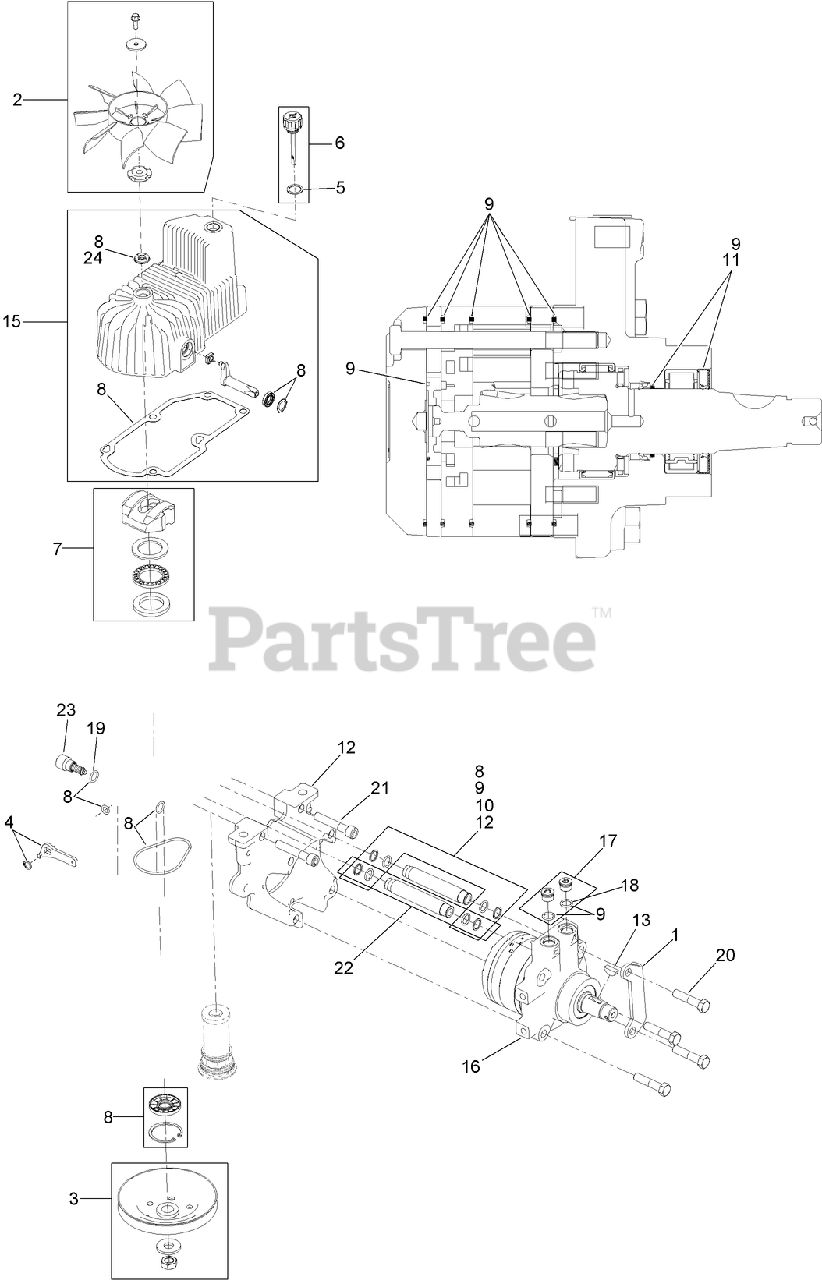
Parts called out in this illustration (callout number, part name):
1	MOUNT-SHOE, HORSE
2	FAN KIT
3	PULLEY KIT
4	HANDLE-BYPASS VALVE, HYDRO
5	GASKET-DIPSTICK, HYDRO
6	DIPSTICK-HYDRO W/GASKET
7	SWASH BLOCK KIT
8	PUMP SEAL KIT
9	MOTOR SEAL KIT
10	TUBE SEAL KIT
11	OUTPUT SHAFT SEAL KIT
12	NOSE CUP-UHT
13	KEY-WOODRUFF
15	HOUSING-HYDRO, RH
16	MOTOR-HYDRAULIC, RH 280CC
17	MAGNETIC PLUGS SERVICE KIT
18	O-RING
19	O-RING-CHECK VALVE
20	SCREW HH
21	SCREW-HSH
22	HYDRAULIC TUBE KIT
23	SHOCK VALVE, 16CC HYDRO
24	SEAL-FAN DRIVE
99	PULLER-PULLEY
